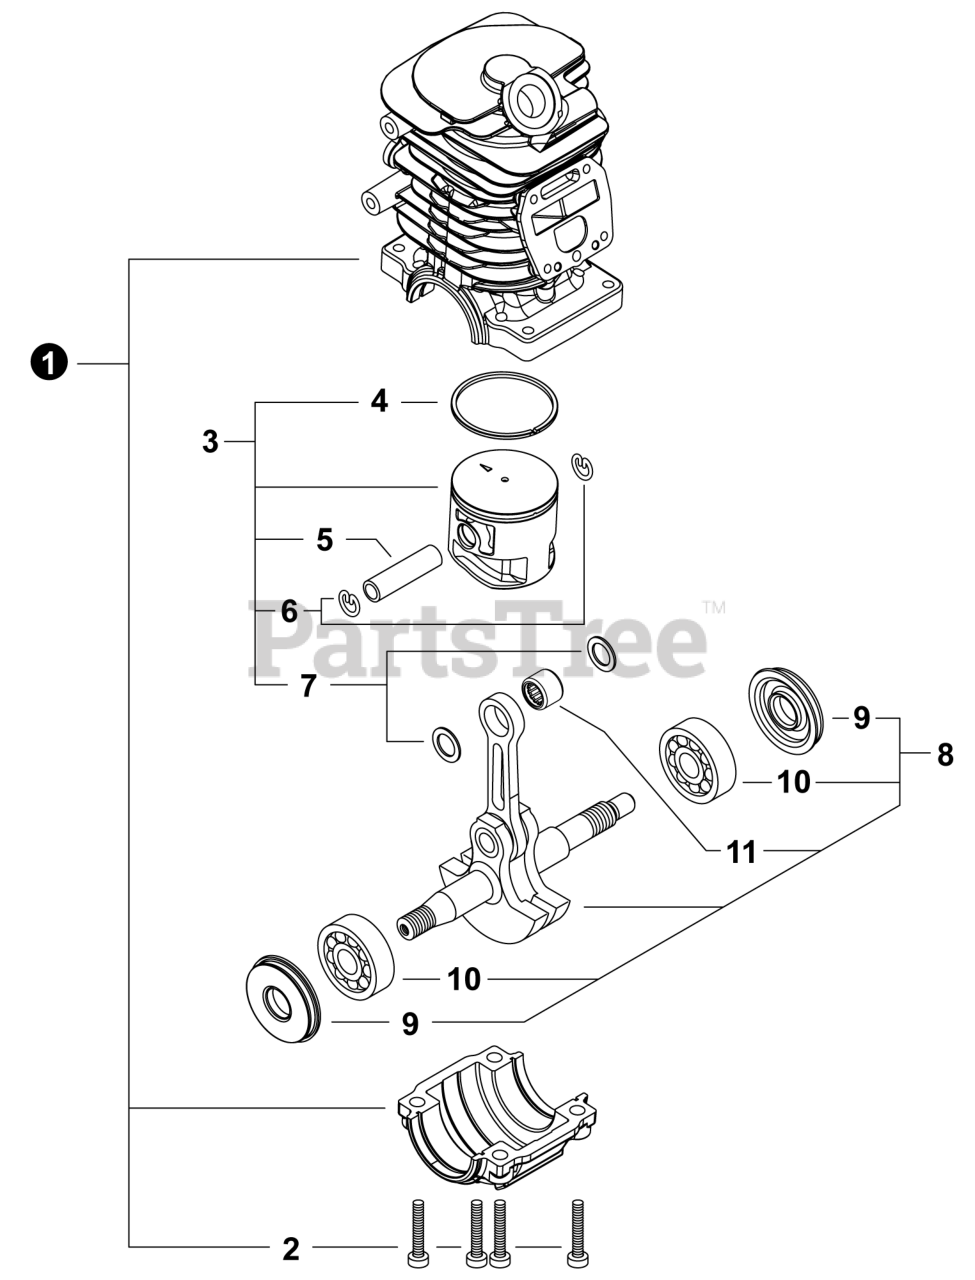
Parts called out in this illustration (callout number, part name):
1	CYLINDER & CRANKCASE SET
2	BOLT, TORX 5x20
3	PISTON KIT
4	RING, PISTON
5	PIN, PISTON 9
6	RING, SNAP
7	WASHER, THRUST
8	CRANKSHAFT ASSY
9	SEAL, OIL 12
10	BEARING, BALL 6201
11	BEARING, NEEDLE 9
